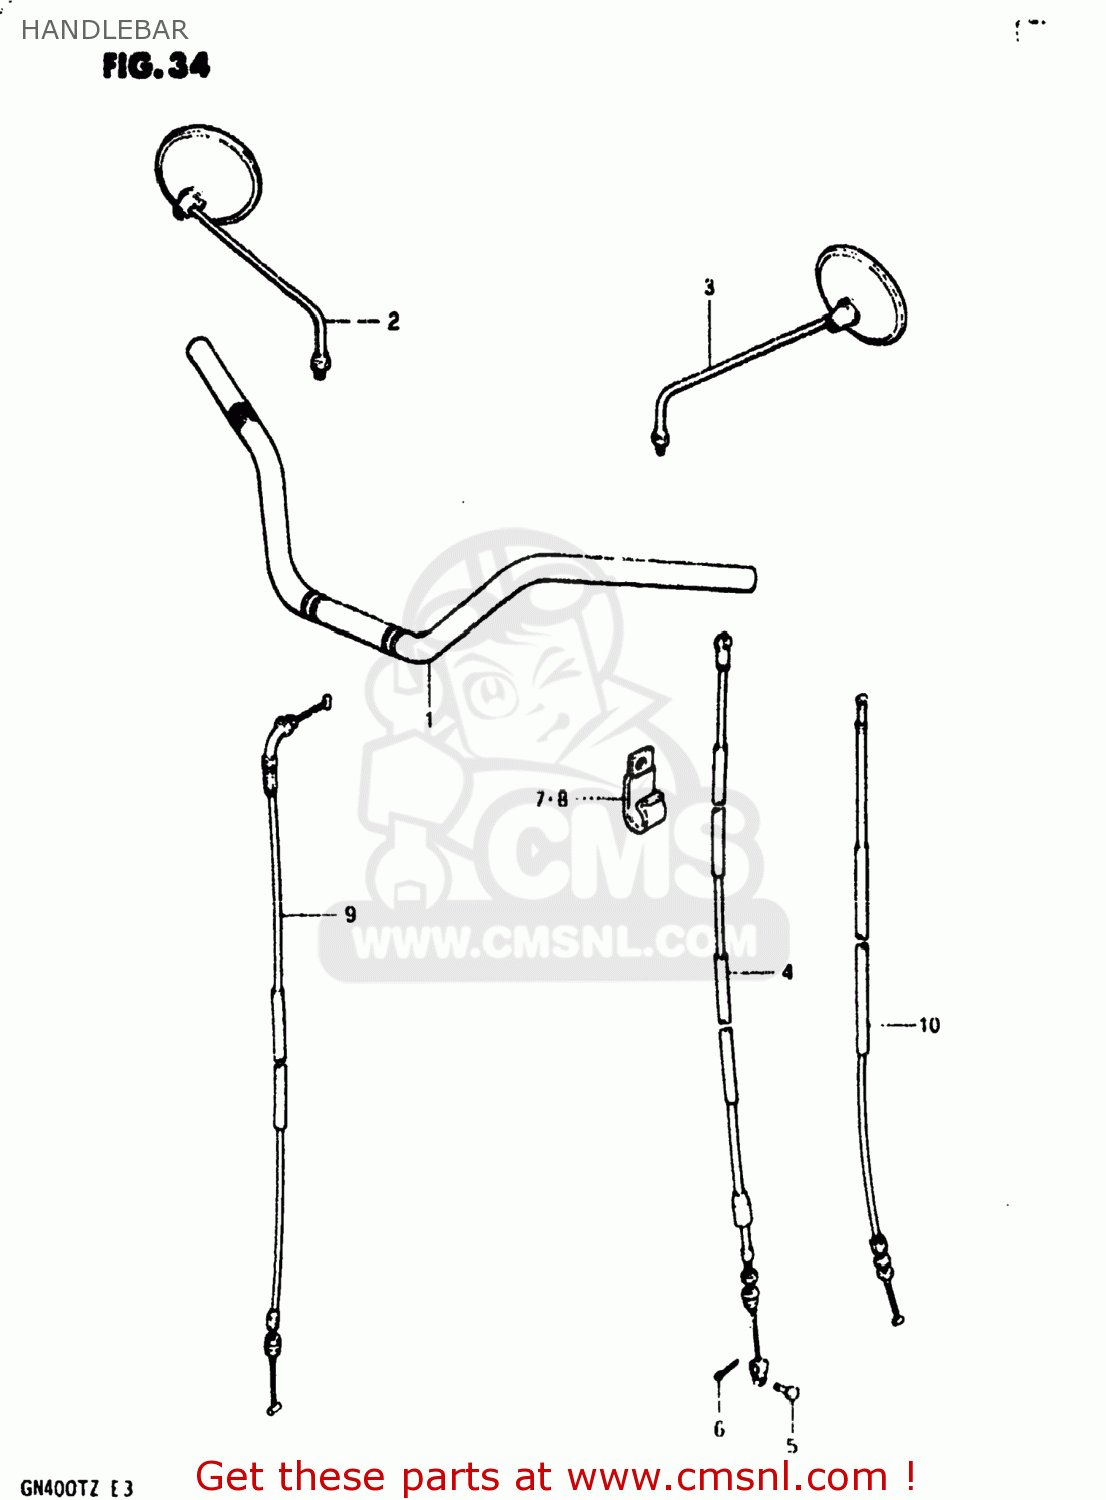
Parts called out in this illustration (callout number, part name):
1	HANDLEBAR
2	MIRROR ASSEMBLY,RIGHT
3	MIRROR ASSEMBLY,LEFT
4	CABLE,CLUTCH
5	PIN(L:15)
6	PIN
7	CLAMP
8	CLAMP
9	CABLE ASSEMBLY,THROTTLE
10	CABLE ASSEMBLY,DECOMPRESSION
